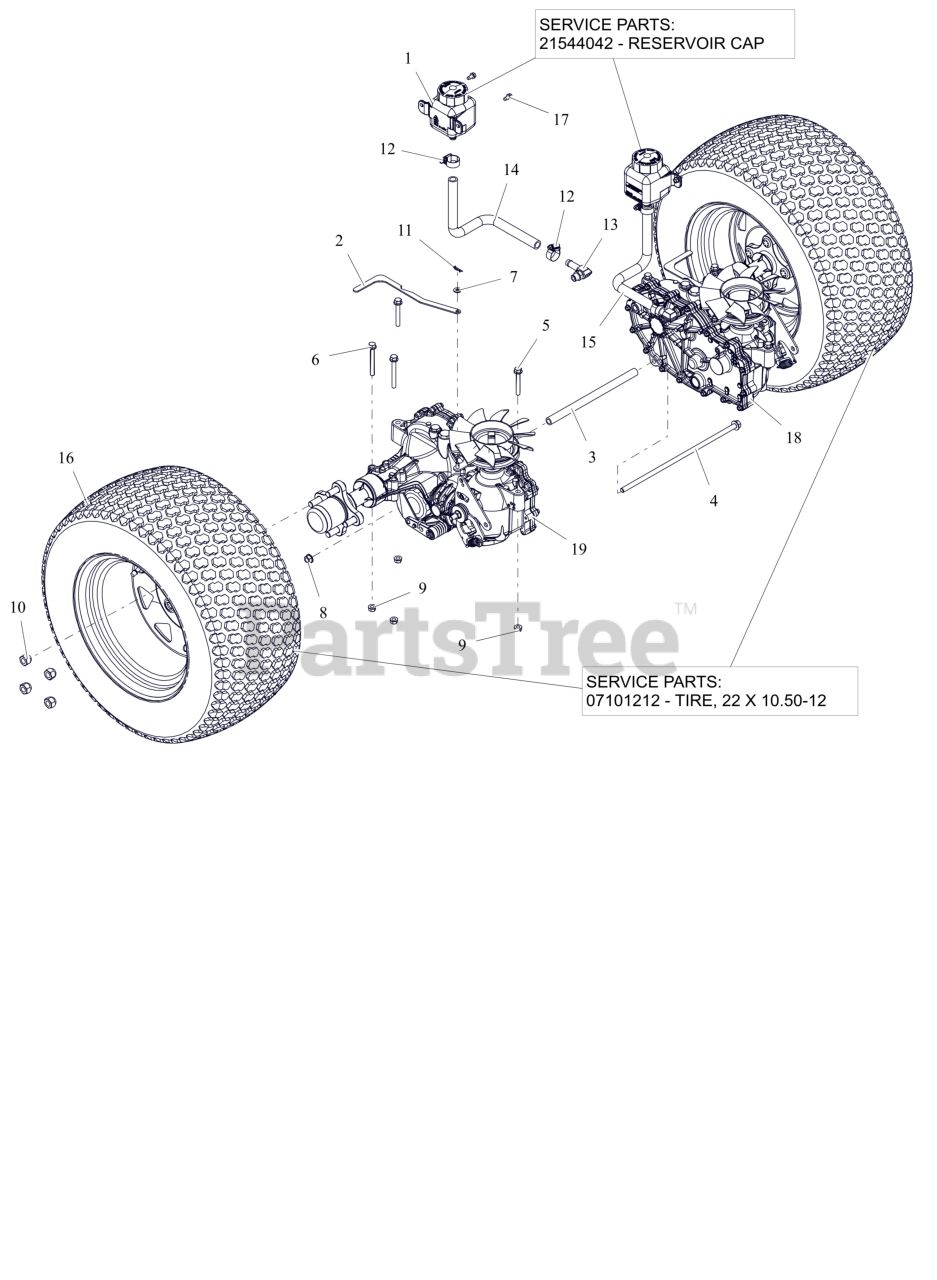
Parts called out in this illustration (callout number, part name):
1	TANK, EXPANSION
1	CAP, HYDRO RESERVOIR REPLAC.
2	BRKT, VALVE DUMP
3	SPCR,TRANS. .406IDX.63ODX9.95L
4	BLT,HEX-FLG .38-16X13 G5 ZCC
5	BLT,HEX-FLG .31-18X2.25 G5 ZCC
6	BLT,HEX-FLG .31-18X2.75 G5 ZCC
7	WSHR,FLT .281X.625X.065 ZCC
8	NUT-LK-TOP-FLG .38-16 ZC120
9	NUT,LK-CTR-FLG .31-18 GF ZCC
10	NUT, WHEEL .50-20 ZCC
11	PIN, HAIR #225 .072X1.09
12	CLAMP,.88 DIA. HOSE
13	FITTING, HYD (90 DEG)
14	HOSE, FORMED EXPANSION -HD RH
15	HOSE, FORMED EXPANSION -HD LH
16	ASM, WHL/TIRE 22X10.50-12 K500
16	TIRE, 22X10.50-12
16	TIRE TUBE 22,23,24/8.50/9.50/10.00/10.50/12.00-12 4 PLY TR13 STRAIGHT VALVE
17	SCR-TAP .25-20X.50 HWH ZCC
18	TRANSAXLE, ZT3100 - LH
19	TRANSAXLE, ZT3100 - RH
